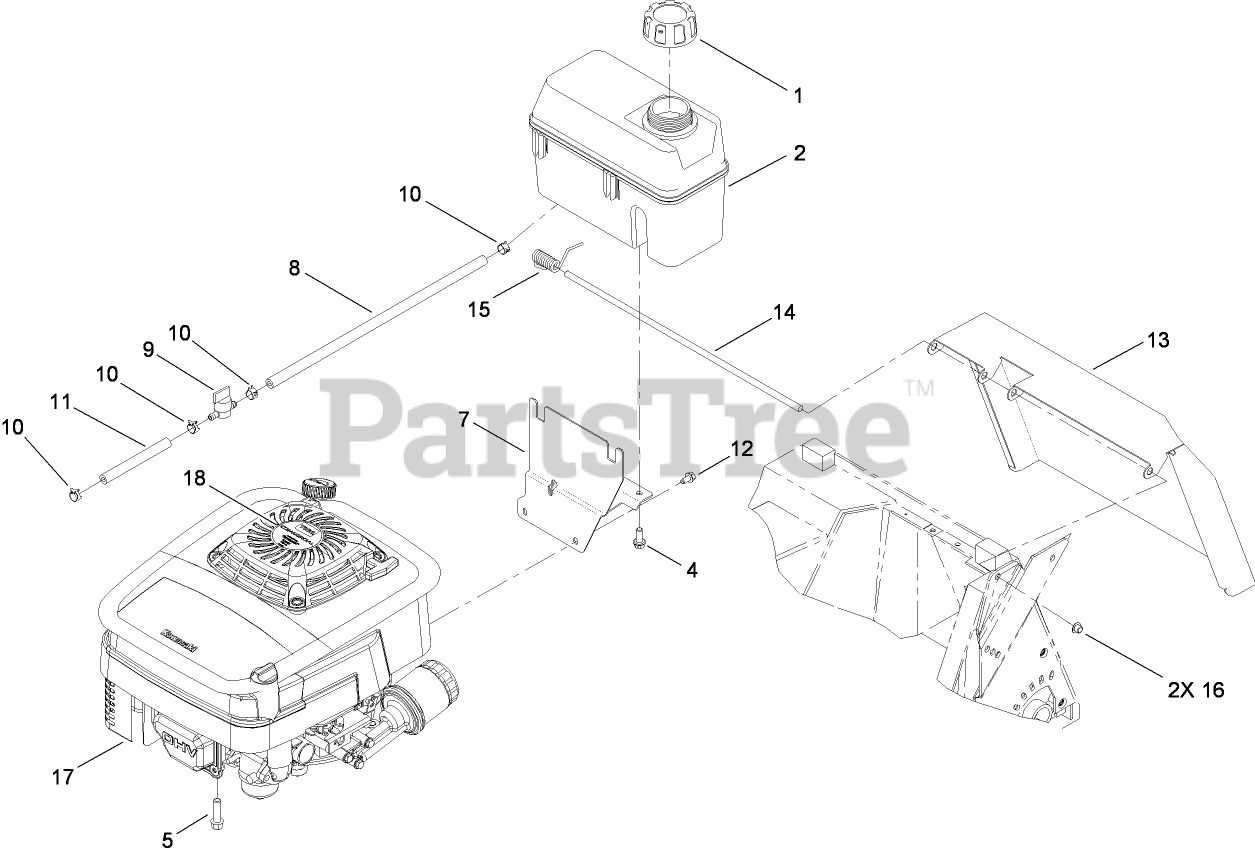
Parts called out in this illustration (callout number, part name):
1	CAP-GAS
2	Tank-Fuel
4	SCREW-HWH
5	SCREW-TAPTITE
7	MOUNT-TANK
8	HOSE-FUEL
9	VALVE-FUEL
10	CLAMP-HOSE
11	HOSE-FUEL
12	SCREW-HWH
13	DOOR-DISCHARGE, REAR
14	ROD-DOOR
15	SPRING-TORSION, DOOR
16	PUSHNUT-CAP, WASHER
17	Engine ASM
